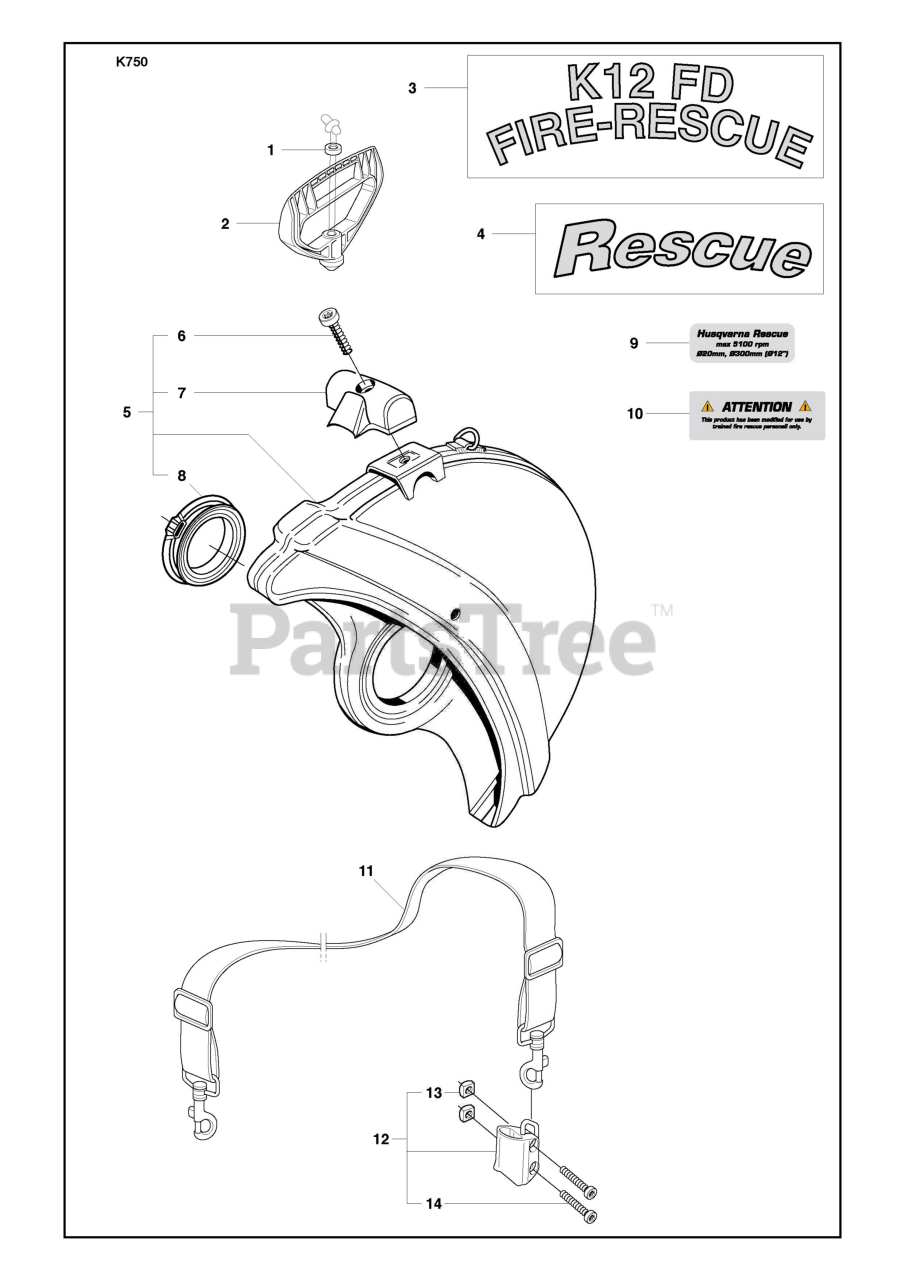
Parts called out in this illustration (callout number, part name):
2	Starter Handle
5	Wheel Guard
11	Shoulder Strap
12	Bracket
